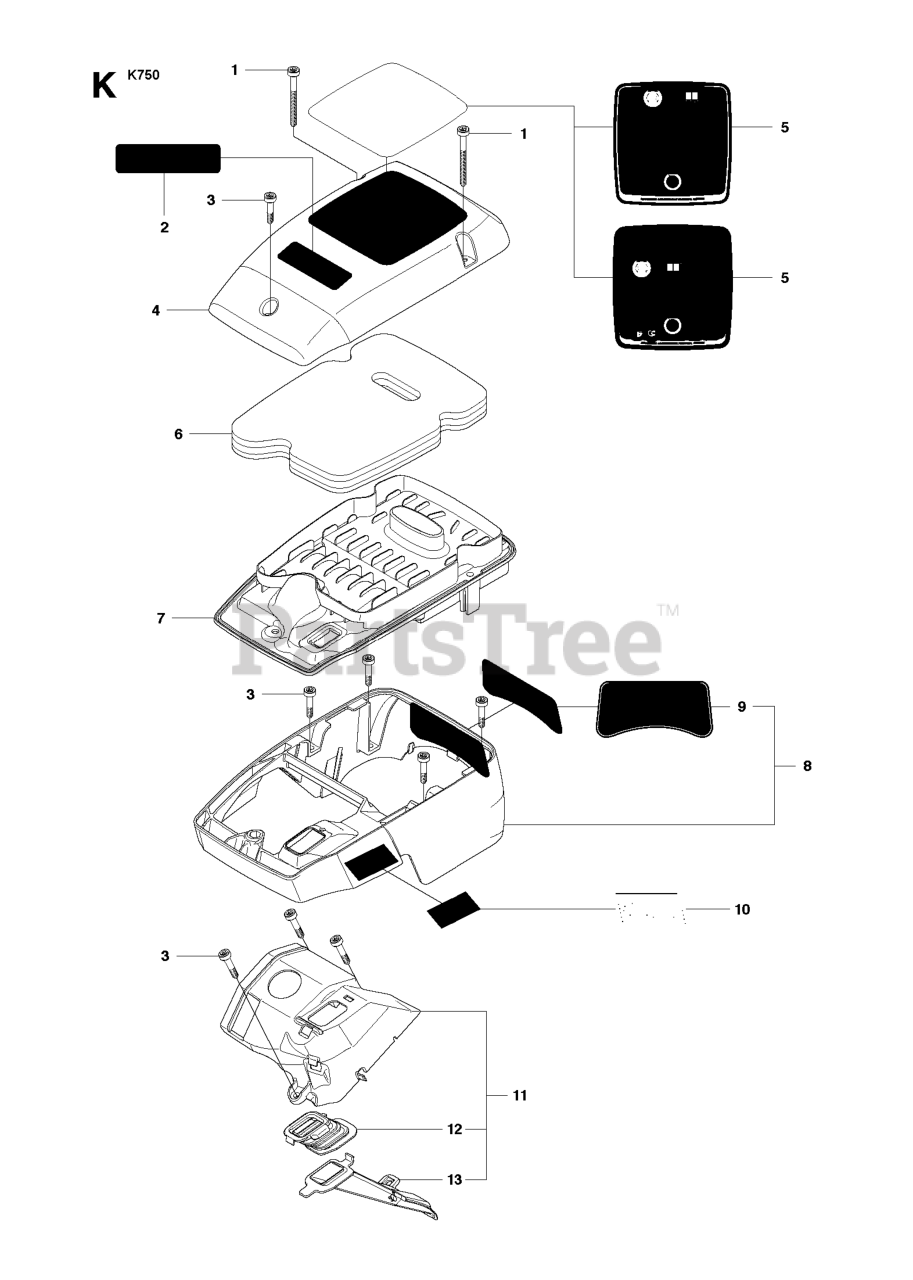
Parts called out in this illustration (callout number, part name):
4	FILTER COVER
5	LABEL EPA2
7	FILTER BOTTOM
8	%CYLINDER COVER ASSY
12	BELLOWS
